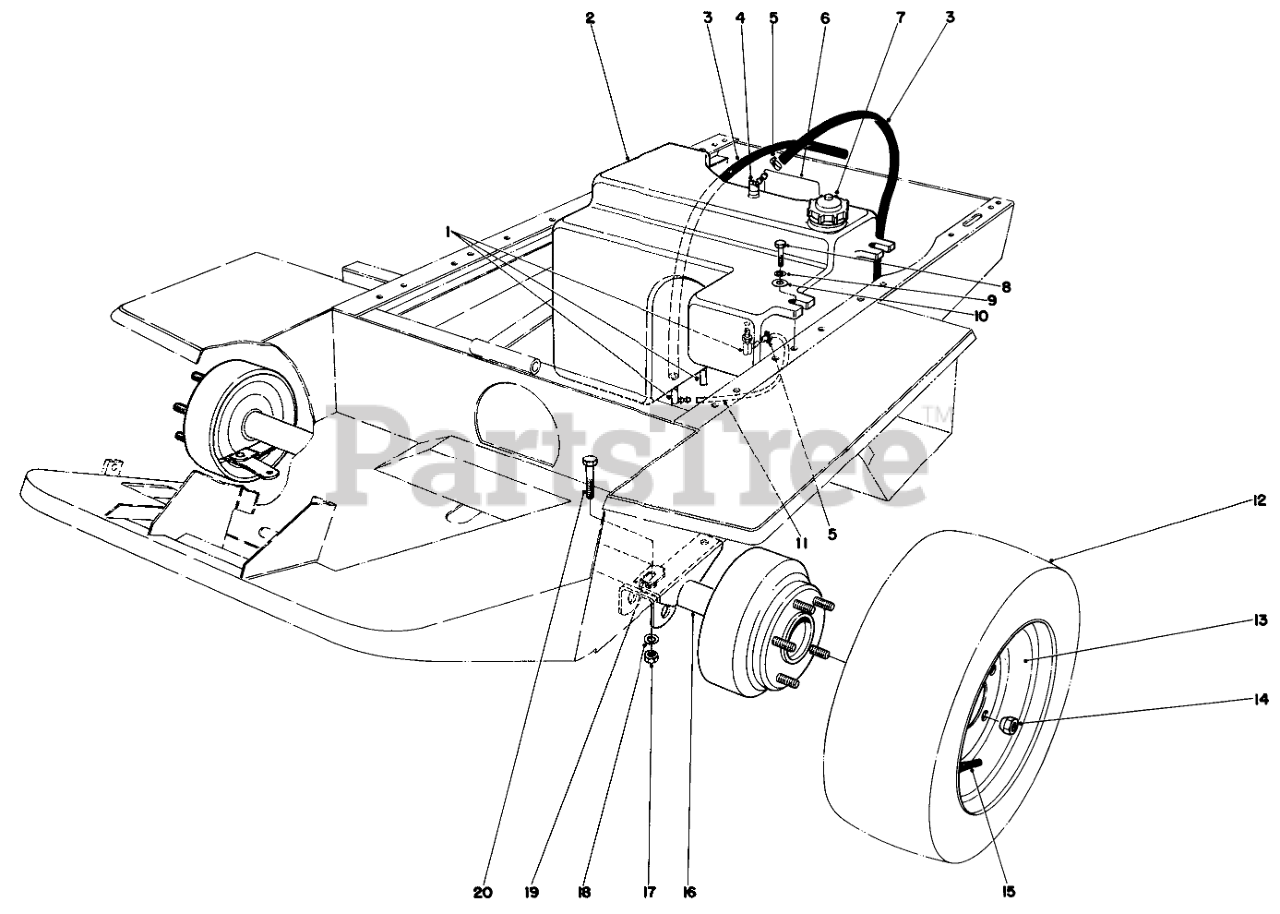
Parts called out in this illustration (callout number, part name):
1	FITTING-ELBOW, 90 DEG
2	Gas Tank (Incl. Ref. #1 & 3)
3	GAS TANK VENT HOSE
4	ELBOW
5	CLAMP-HOSE
6	DECAL-DANGER
7	Gas Cap
8	SCREW-HH
9	WASHER-LOCK
10	WASHER
11	HOSE-FUEL
12	20 X 8.00 - 10 TIRE
13	WHEEL ASM
14	NUT-WHEEL
15	VALVE STEM AND CAP ASM
17	NUT-HEX
18	WASHER-LOCK
19	SHIM-AXLE
20	SCREW-HH
